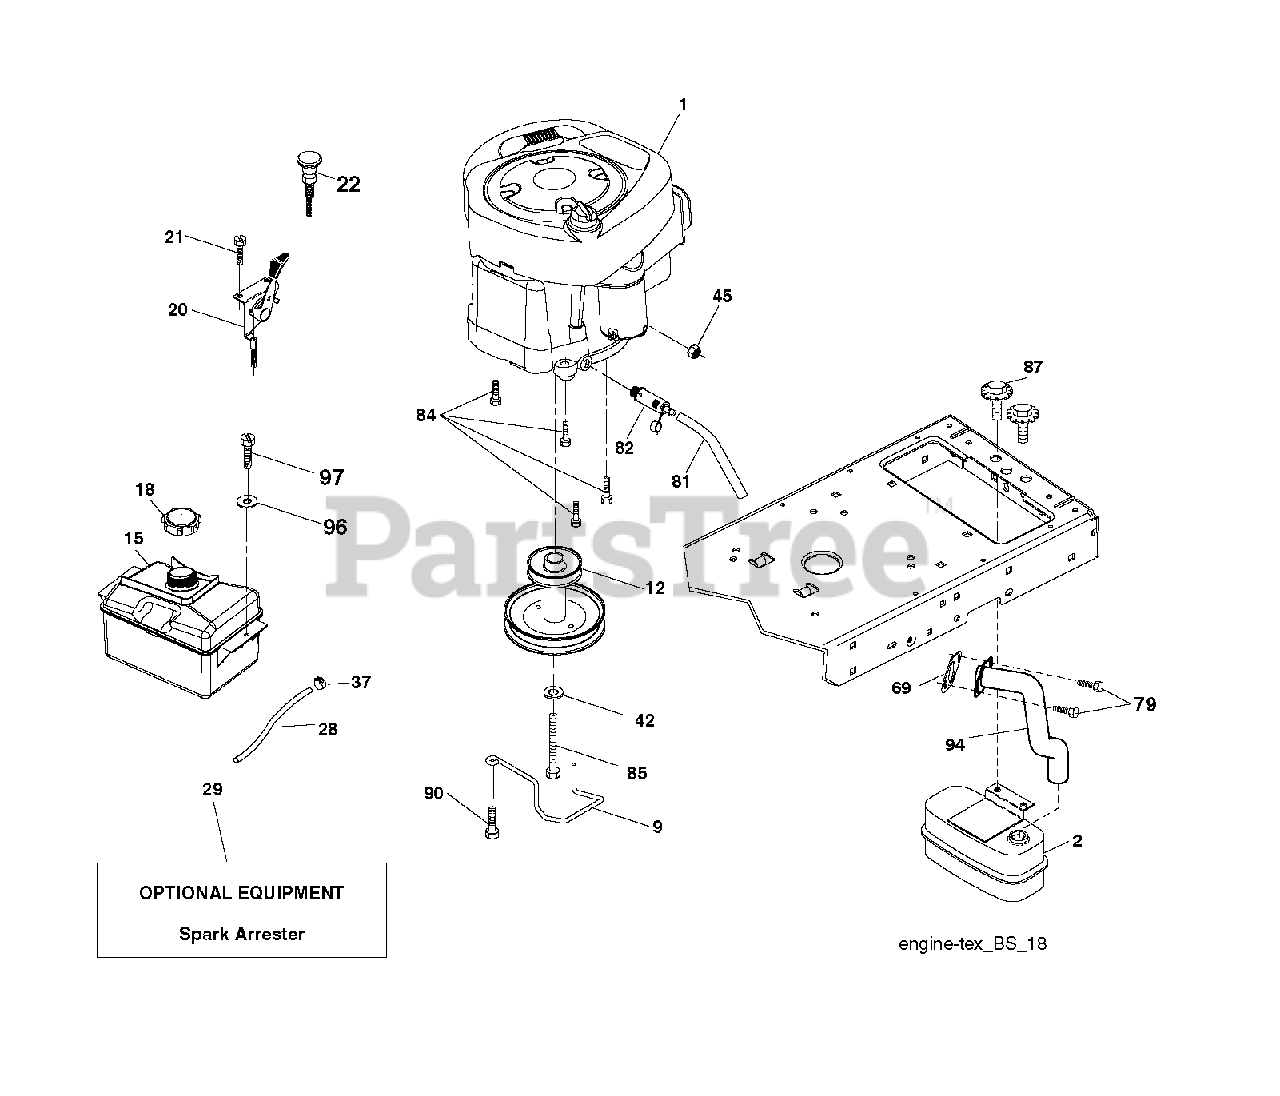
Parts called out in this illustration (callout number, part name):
2	MUFFLER.SINGLE.CYL.KOHL/B&S
9	KEEPER.BELT.ENGINE.3.25
12	PULLEY ENGINE
15	TANK FUEL FRT 1.5 GAL
18	FUEL CAP
20	CONTROL.TH/CK.C.
21	SCREW.#10 X 0.750.BOS THREAD
28	LINE.FUEL.20
29	ARRESTER SPARK (OPTIONAL)
37	HOSE CLAMP
42	LOCKWASHER
45	NUT
69	REPL BY 532 27 22-93
79	SCREW.SOCKET HD.5/16-1
81	TUBE, DRAIN OIL ASM.
82	PLUG DRAIN OIL EASY
84	SCREW.3/8-16
85	BOLT HEX 7/16-20X4-1/4"
87	BOLT, 5/16-18 X 1 3/4
90	SCREW 3/8-16X1
94	EXHAUST.TUBE.B&S.
97	SCREW HEXWSHR 1/4-20X3/4
